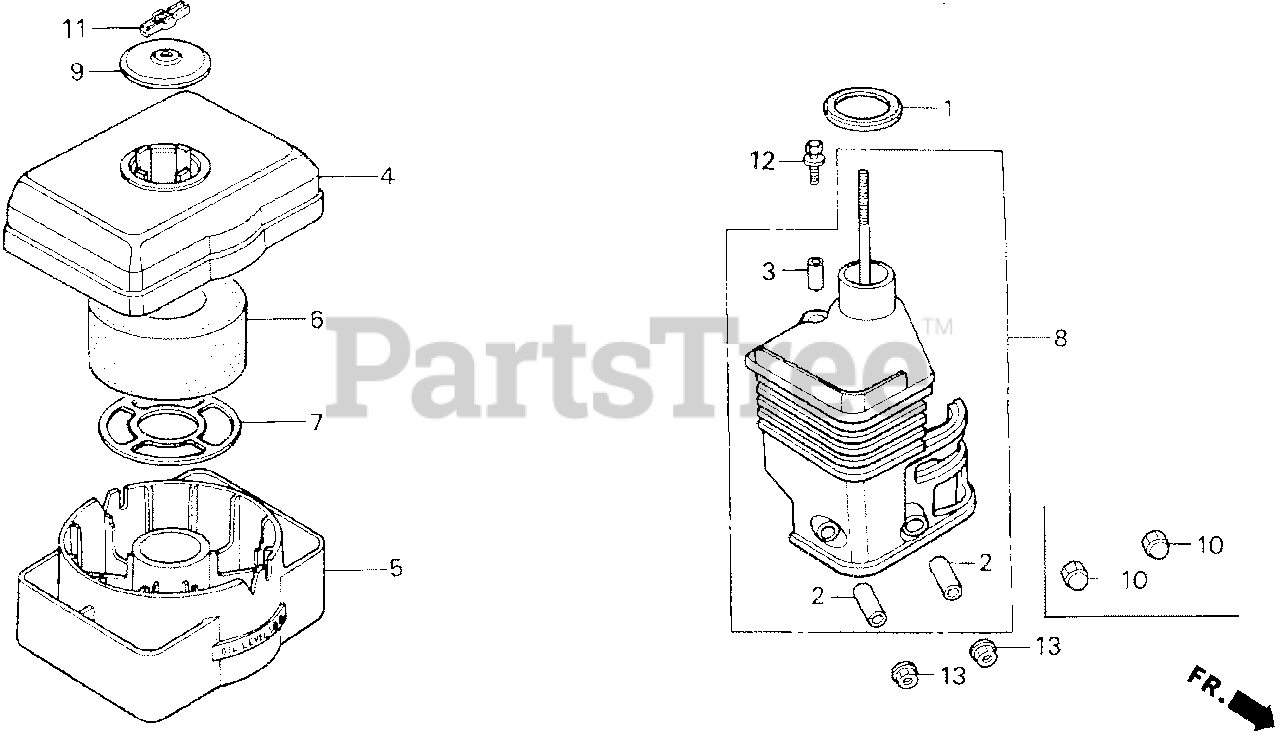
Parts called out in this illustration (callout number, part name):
1	GASKET, ELBOW
2	COLLAR, AIR CLEANER
3	COLLAR B, AIR CLEANER
4	BODY, CLEANER (OIL BATH)
5	PAN, CLEANER OIL (OIL BATH)
6	ELEMENT, AIR CLEANER (OIL BATH)
7	GRID, AIR CLEANER
8	ELBOW, AIR CLEANER
9	CAP, CLEANER
10	NUT, CAP (6MM)
11	WINGNUT, AIR CLEANER COVER
11	WINGNUT (6MM)
11	WINGNUT, TOOL BOX SETTING
12	BOLT-WASHER (6X20)
13	NUT, FLANGE (6MM)
